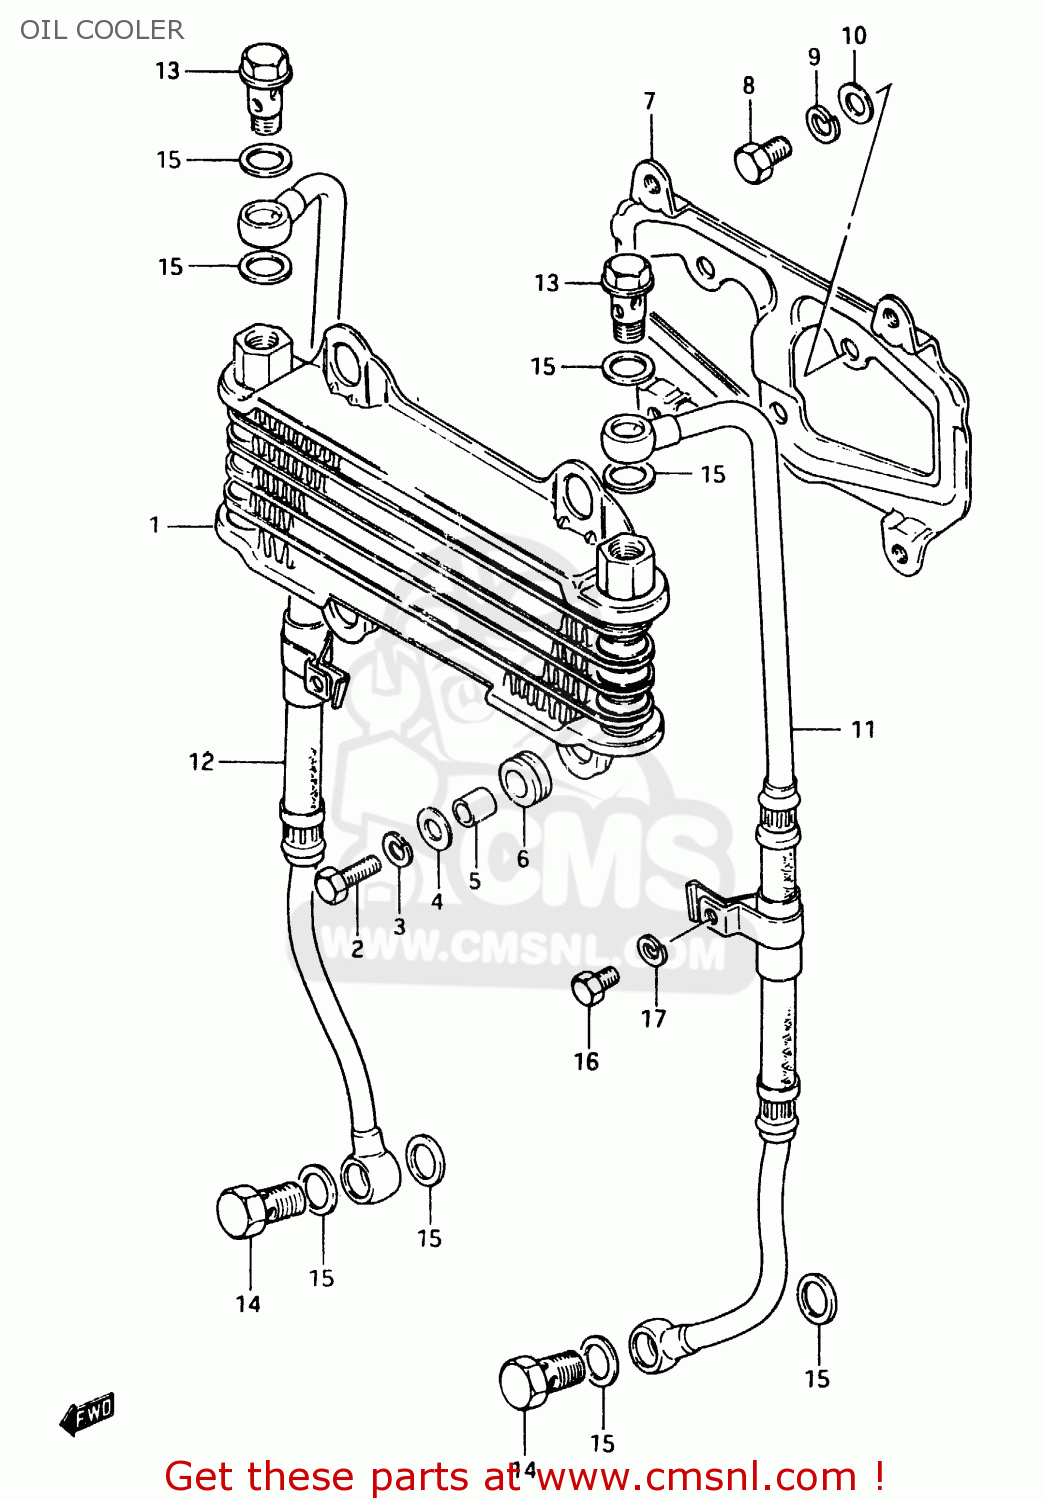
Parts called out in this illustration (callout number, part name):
1	COOLER ASSEMBLY,ENGINE OIL
2	BOLT
3	LOCK WASHER
4	WASHER (6.5X18X1.6)
5	SPACER (6.8X10X10)
6	CUSHION
7	BRACKET,OIL COOLER
8	BOLT
9	LOCK WASHER
10	WASHER,8.5X16X
11	HOSE,ENGINE OIL,LEFT
12	HOSE,ENGINE OIL,RIGHT
13	BOLT UNION
14	BOLT UNION
15	GASKET(14X20X1.5) (NAS)
16	BOLT
17	LOCK WASHER
